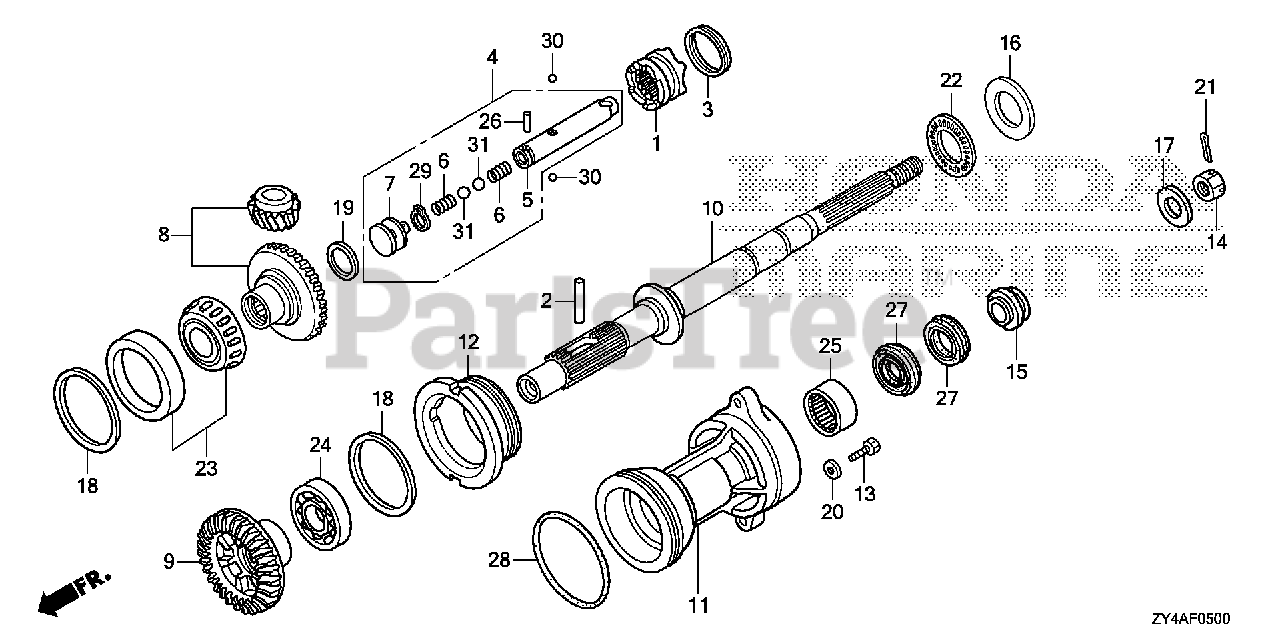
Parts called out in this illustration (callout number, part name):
1	SHIFTER, CLUTCH
2	PIN, SHIFTER (8X50)
3	RING, CROSS PIN
4	SLIDER, SHIFT
5	SLIDER, SHIFT
6	SPRING, SHIFT
7	PLATE, SHIFT
9	GEAR, BEVEL (RVS. 28T)
10	SHAFT, PROPELLER
11	HOLDER, PROPELLER SHAFT *NHB14M* (AQUA MARINE SILVER METALLIC)
12	HOLDER, BEARING
13	BOLT, HEX. (12X45)
14	NUT, CASTLE (18MM)
15	WASHER, PROPELLER THRUST
16	WASHER, THRUST BEARING
17	WASHER, PROPELLER
18	SHIM A, BEVEL (0.10)
18	SHIM B, BEVEL (0.15)
18	SHIM C, BEVEL (0.30)
18	SHIM D, BEVEL (0.50)
19	SHIM A, THRUST (2.75)
19	SHIM B, THRUST (2.80)
19	SHIM C, THRUST (2.85)
19	SHIM D, THRUST (2.90)
19	SHIM E, THRUST (2.95)
19	SHIM F, THRUST (3.00)
19	SHIM G, THRUST (3.05)
19	SHIM H, THRUST (3.10)
19	SHIM I, THRUST (2.70)
19	SHIM J, THRUST (2.65)
19	SHIM K, THRUST (2.60)
19	SHIM L, THRUST (2.55)
19	SHIM M, THRUST (2.50)
20	WASHER, PLAIN (12MM)
21	PIN, SPLIT (4.0)
22	BEARING, THRUST (F)
23	BEARING, TAPER (50X90X21.5)
24	BEARING, ANGULAR (50X90X30.2)
25	BEARING, NEEDLE (32X42X30)
26	ROLLER (3X13.8)
27	SEAL, WATER (30X45X7)
28	O-RING (110X3.1)
29	CIRCLIP (OUTER) (15MM)
30	BALL, STEEL (#7) (7/32)
31	BALL, STEEL (#12) (3/8)
